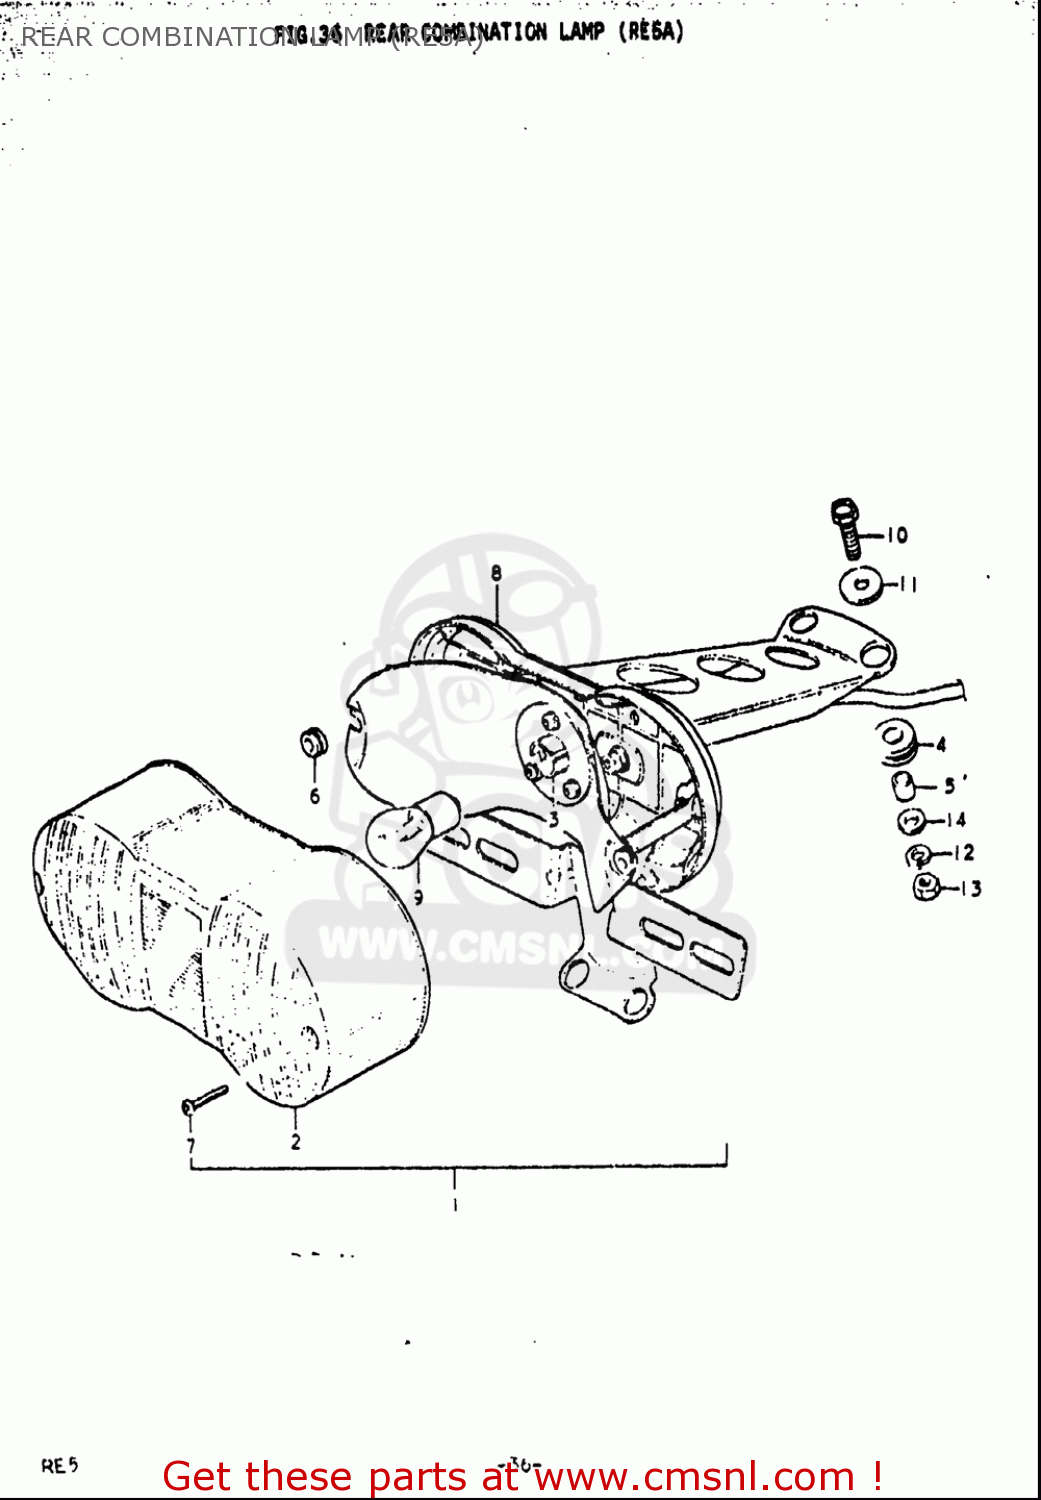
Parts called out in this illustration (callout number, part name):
2	LENS,RR COMBINATION LAMP
4	CUSHION
5	SPACER
6	CUSHION
7	SCREW
8	HOUSING,RR COMBINATION LAMP
9	BULB(12V23W)
10	BOLT
11	WASHER(6.5X20X1.6)
12	WASHER,LOCK
13	NUT
14	WASHER
